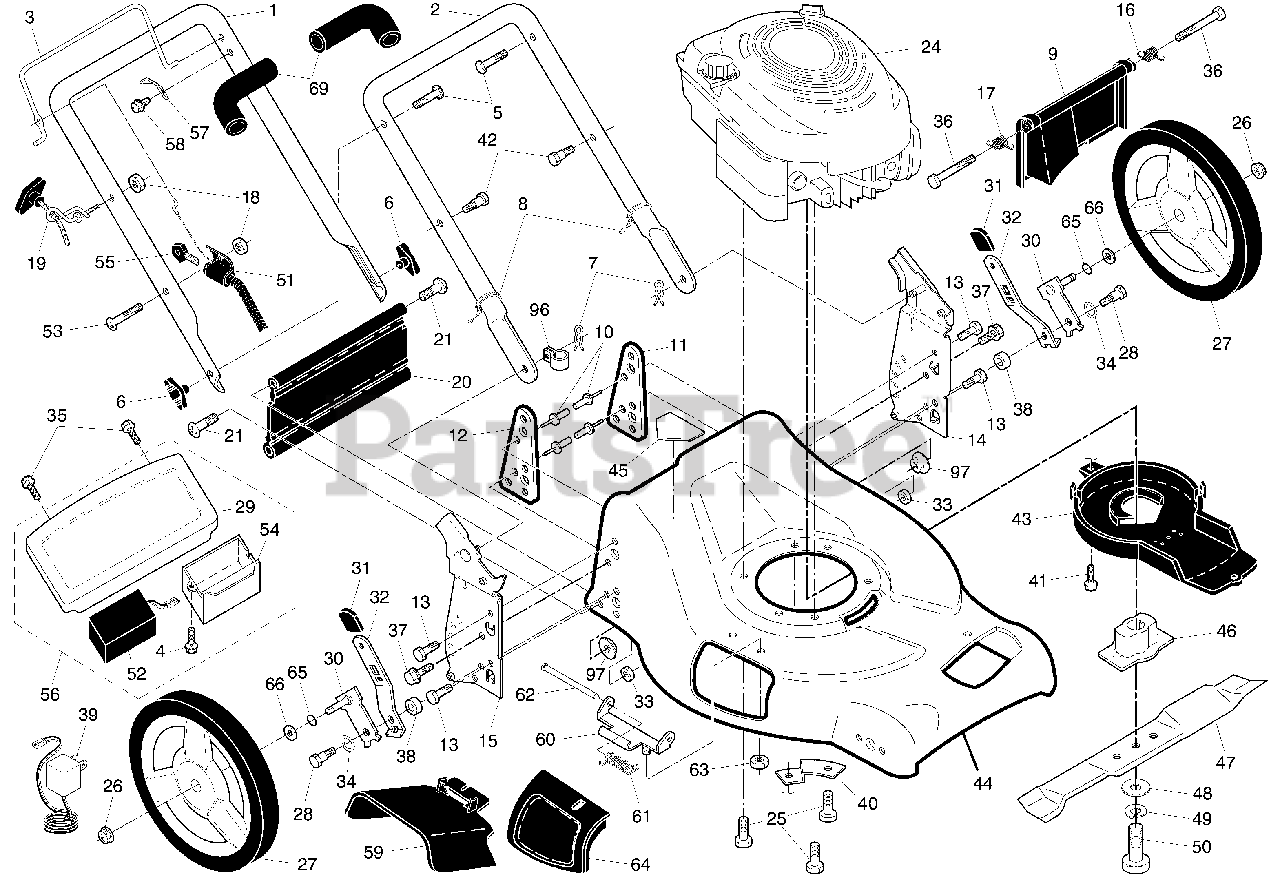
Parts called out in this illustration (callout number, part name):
1	Upper Handle
2	Lower Handle
3	Control Bar
5	Handle Bolt
6	Handle Knob
7	Hairpin Cotter
8	Wire Tie
9	Rear Door Assembly
11	Support Bracket, LH
12	Support Bracket, RH
13	Screw 1/4-20 x 5/8
14	Handle Bracket Assembly, LH
15	Handle Bracket Assembly, RH
16	Spring, Rear Door, LH
17	Spring, Rear Door, RH
18	Keps Locknut 1/4-20
19	Rope Guide
20	Rear Skirt
25	Hex Head Thread Rolling Screw 3/8-16 x 1-1/8
26	Hex Flange Nut
27	Wheel & Tire Assembly, Rear
28	Shoulder Bolt 5/16-18 x .33
29	Trim Panel
30	Axle Arm Assembly
31	Selector Knob
32	Selector Spring
33	Nut, Hex 5/16-18
34	Washer, Curved, Cylindrical
37	Bolt
39	Charger, Battery
40	Mounting Bracket, Debris Shield
43	Debris Shield
44	Kit, Lawn Mower Housing
45	Danger Decal
46	Blade Adapter
47	Blade, 21"
48	Hardened Washer
49	Helical Washer 3/8-24 x 1-3/8 Grade 8
50	Hex Head Machine Screw 3/8-24 x 1-3/8 Grade 8
51	Key Start Switch
52	Battery
54	Battery Box
56	Trim Panel / Battery / Battery Box Assembly
57	Upstop Bracket
59	Discharge Deflector
60	Hinge Bracket
63	Nut, Hex
64	Mulcher Door
66	Washer, Flat 1/2
69	Grip, Foam
96	Clip, Cable
97	Nut, Hex, Flangelock
